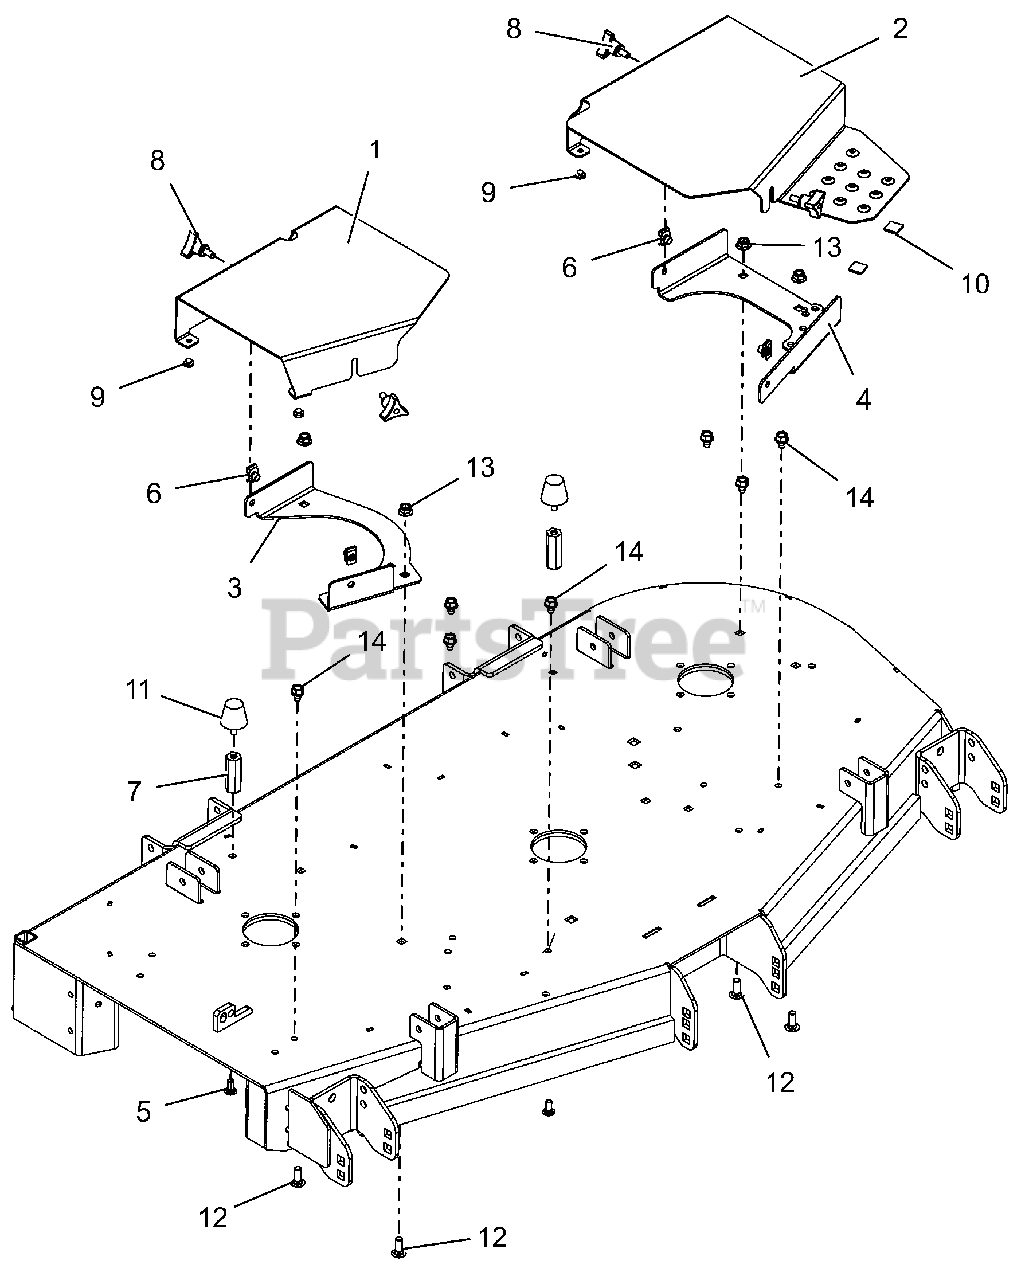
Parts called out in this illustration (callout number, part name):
1	GUARD, RH DECK - RED
2	GUARD, LH BELT - RED
3	BRKT, BELT GUARD RH MOUNTING (RED)
4	BRKT, BELT GUARD LH (RED)
5	BLT,RDHDSQNK .31-18X.75 LOCTIT
6	NUT-CLIP RETAINER 5/16-18X.56
7	NUT, .31-18X2.25 LG COUPLING
8	KNOB,WING STUD 5/16-18 X .75
9	BUMPER GROMMET
11	BUMPER, RUBBER CONE,STUD MOUNT
12	@BLT-RDHDSQNK .38-16X1.00 G5YZ
13	@NUT-LK-NYL-FLG .38-16 YWZC
14	@SCR-TAP .38-16X.50 HWH TR YWZ
